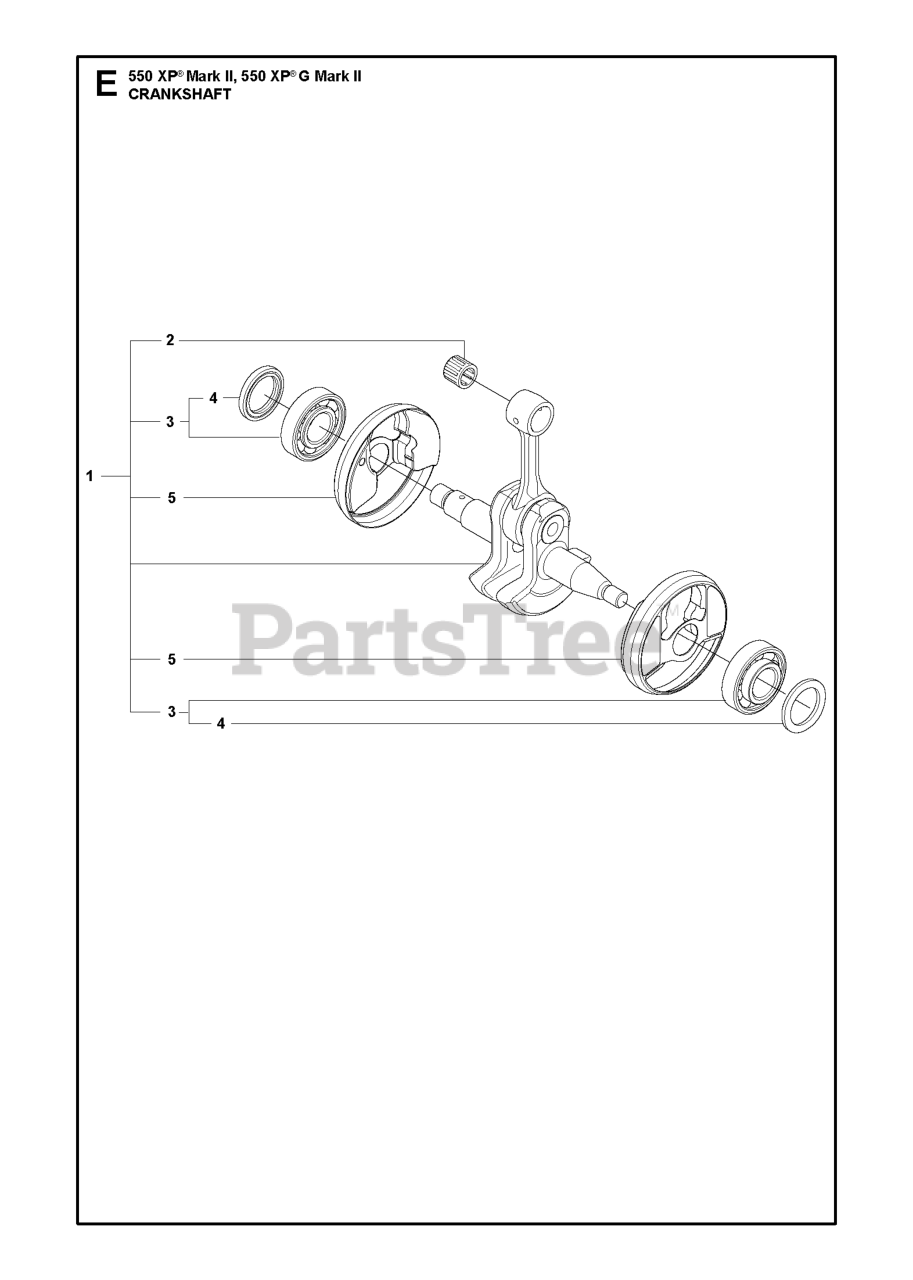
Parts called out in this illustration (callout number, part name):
1	CRANKSHAFT KIT SPARE PART H550
2	NEEDLE BEARING
3	BALL BEARING
4	RADIAL SEAL
